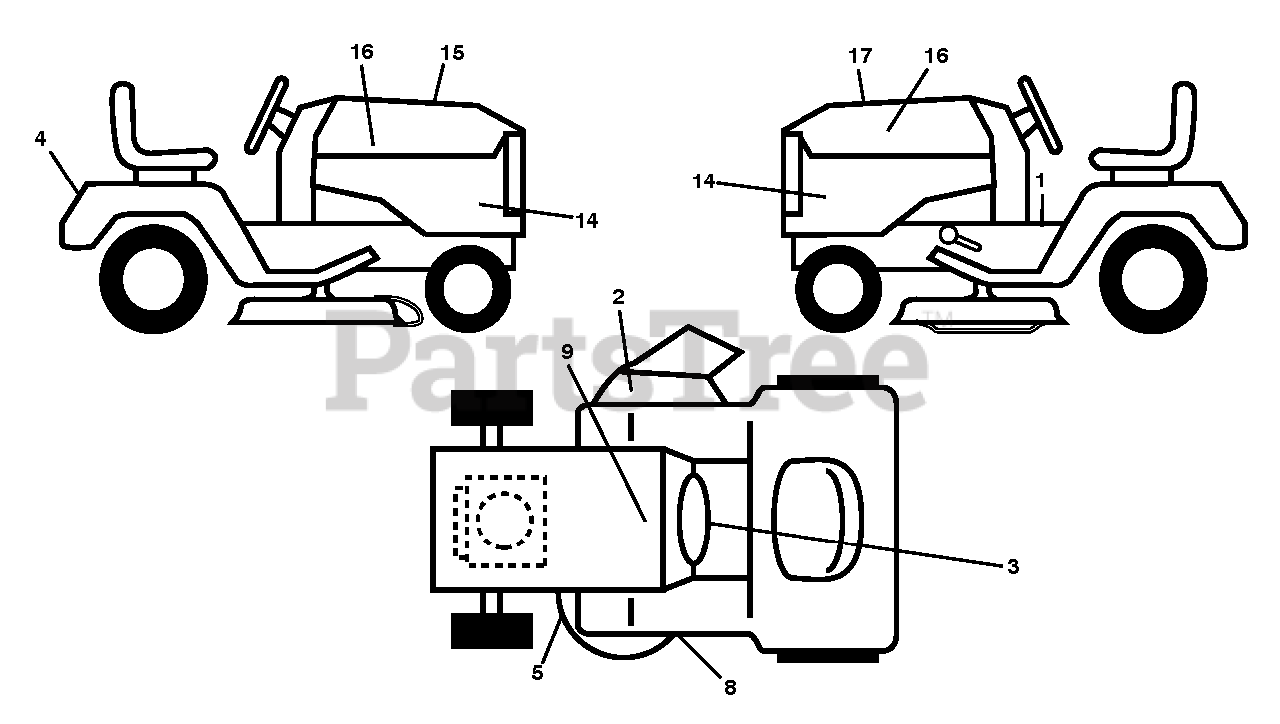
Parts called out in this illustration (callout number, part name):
1	DECAL.WARN.STARTINST.LOWEARIEN
2	DECAL.MOWER.WARN.KEEP.HAND.AWY
3	DECAL, WARNING SPARK ARRESTOR
4	DECAL.FENDER
5	DECAL.MOWER.CAUTION.TENSION.AR
8	DECAL.MOWER.SCH.48/54.PREM
9	DECAL BTRY SYMBOLS
14	DECAL.SIDE.PANEL.YTH24K48
15	DECAL.WARNING.CUST.RESP.E85.
16	DECAL.BADGE.170MM.TEXTLOGO.
